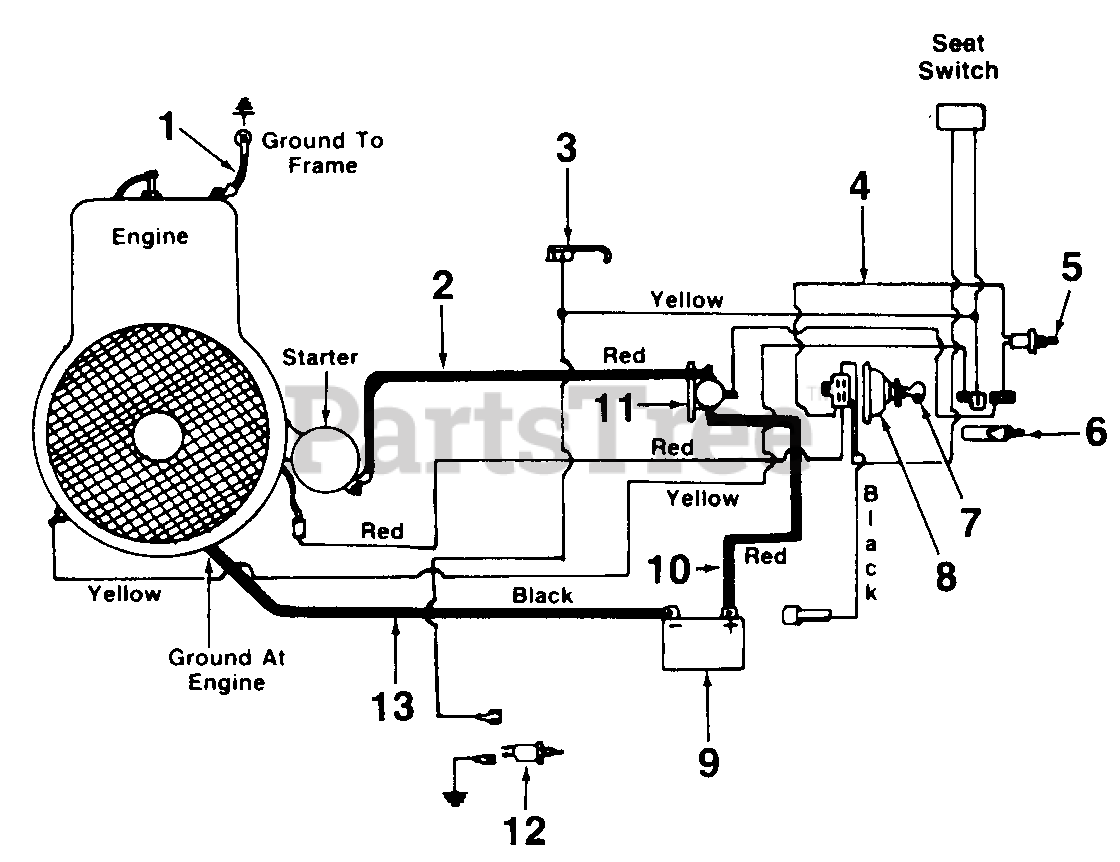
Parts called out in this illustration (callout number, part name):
1	Elec. Wire 8 Ga. x 9.0" Lg.
2	Elec. Wire
3	Spring Switch-Reverse
4	Wire Harness
5	Safety Switch-Black N.O.
6	Safety Switch
7	Ignition Key
8	Ignition Switch
9	Battery 12V
10	Elec. Wire Red w/Boot
11	Solenoid
12	Safety Switch Red N.C.
13	Elec. Wire 8 Ga. x 9.0" Lg.
